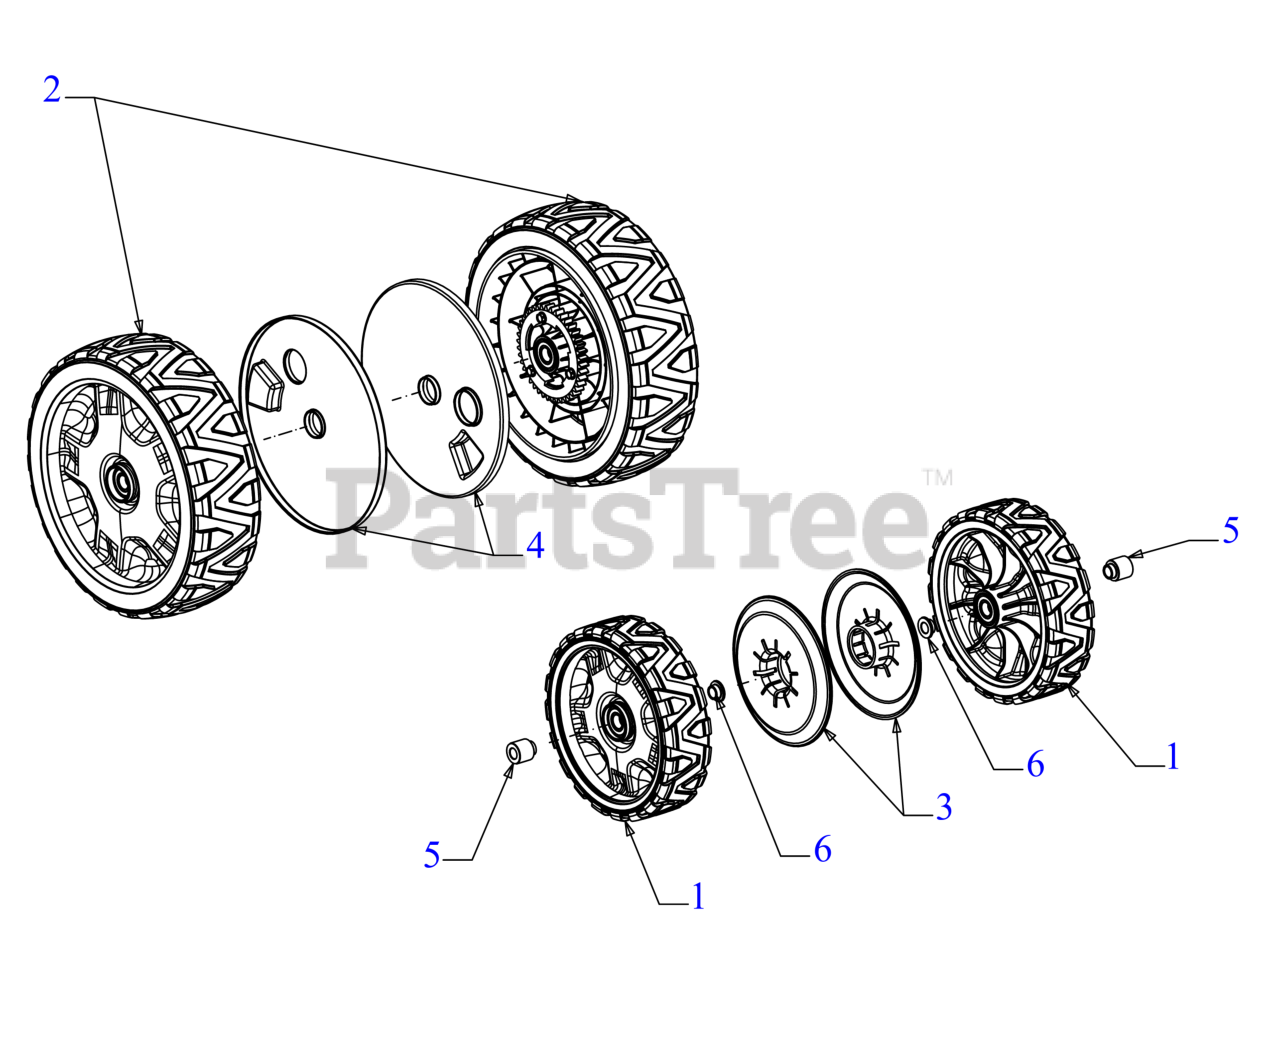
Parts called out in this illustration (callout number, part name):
1	WHEEL ASSEMBLY (7 x 2)
2	DRIVE WHEEL ASSEMBLY 10 x 3 (CRAFTSMAN)
3	7" DUST COVER
4	DUST COVER 10"
5	CASTER HUB
6	CASTER HUB
